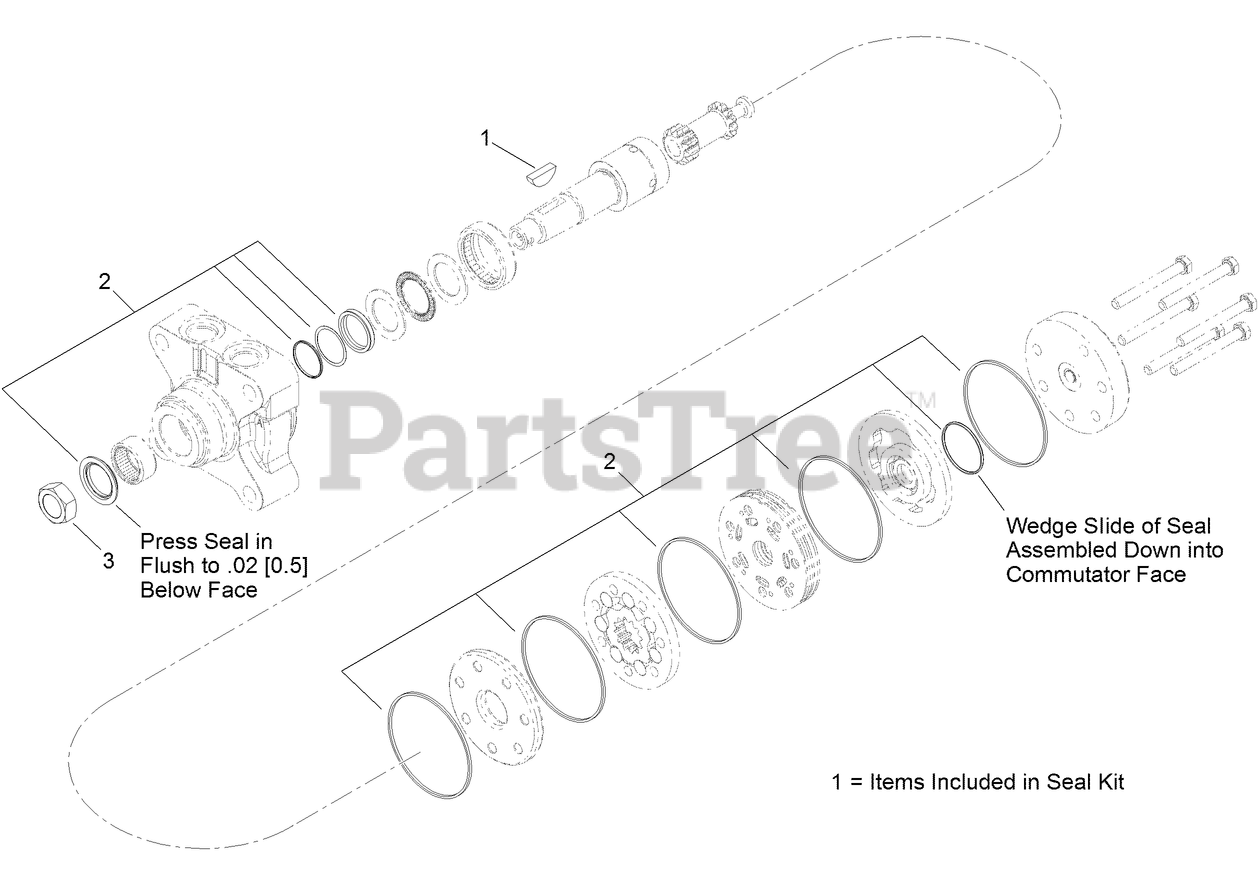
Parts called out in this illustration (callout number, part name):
1	KEY-WOODRUFF
2	SEAL KIT
3	NUT-LOCK
